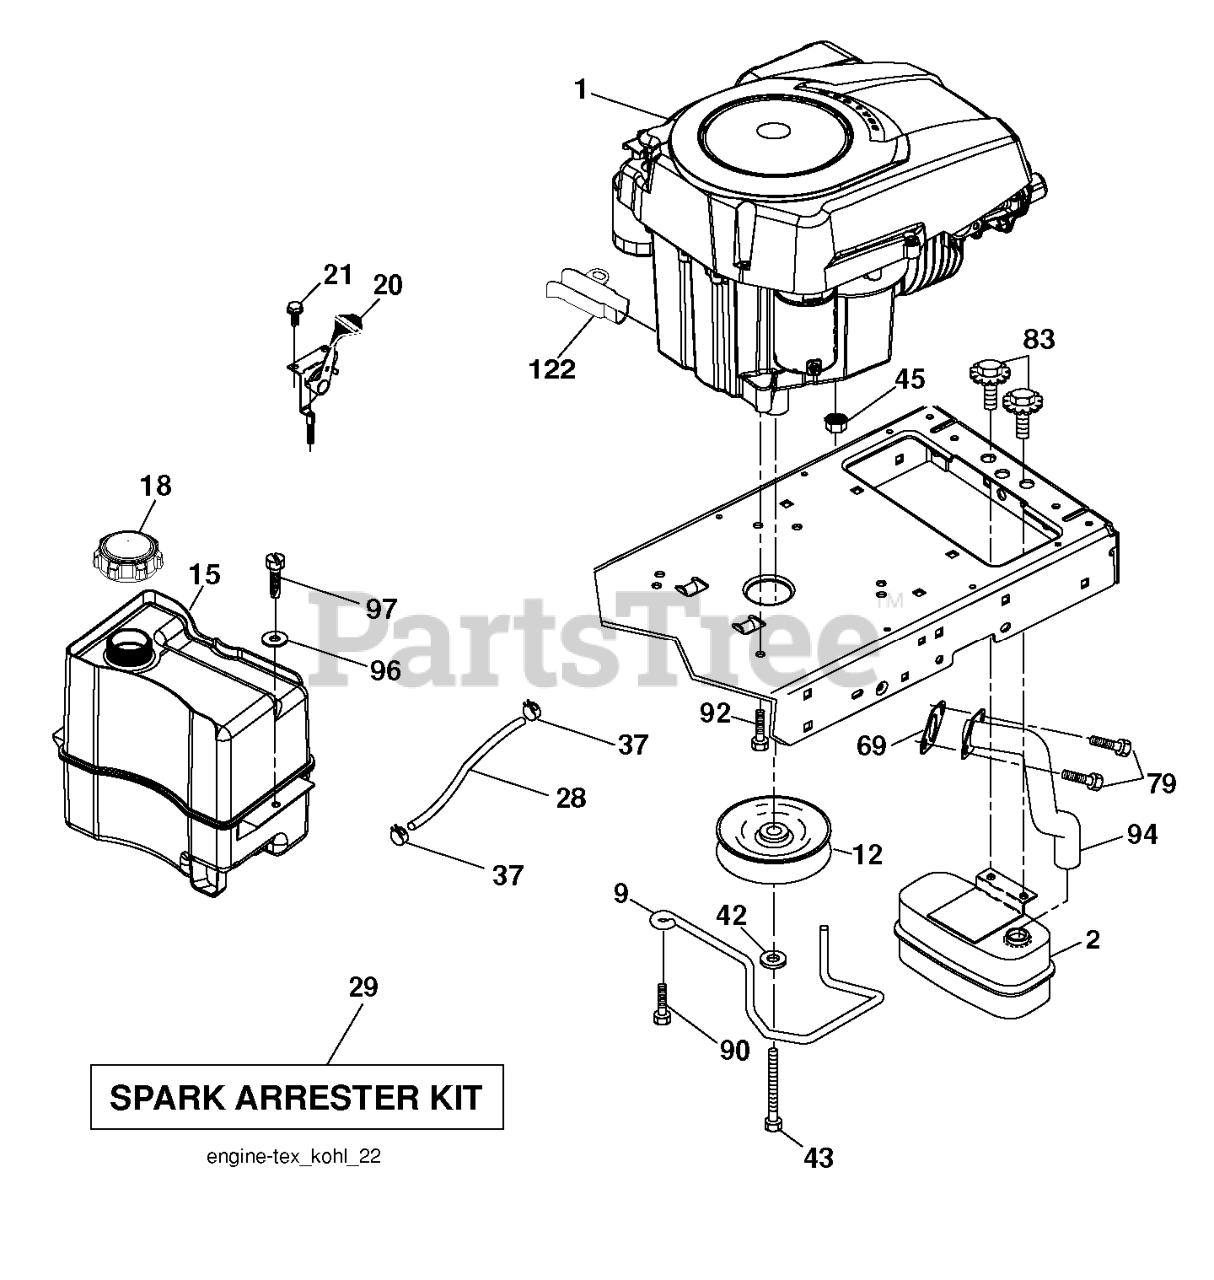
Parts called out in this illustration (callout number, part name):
2	MUFFLER.SINGLE.CYL.KOHL/B&S
9	KEEPER.BELT.ENGINE.3.25 (3 2)
12	PULLEY ENGINE
15	RP TANK FUEL FRT 1.5 GAL
18	CAP ASM.FUEL.2.25"FR.
20	CONTROL.TH/CK.C.
21	SCREW.#10 X 0.750.BOS
28	LINE.FUEL.20
29	KIT.SPARK ARRESTOR 794945 B&S
37	HOSE CLAMP
42	LOCKWASHER
43	BOLT HEX 7/16-20X4-1/4"
45	NUT
69	GASKET.EXHAUST.KOHLER
79	SCREW.SOCKET HD.5/16-1
83	BOLT.5/16-18UNCX3/4 W/SEMS.BLK
90	SCREW 3/8-16X1
92	SCREW 3/8-16X1
94	RP.TUBE.EXHAUST.KOHL.COURAGE
97	SCREW HEXWSHR 1/4-20X3/4
122	EXTENSION DRAIN OIL
